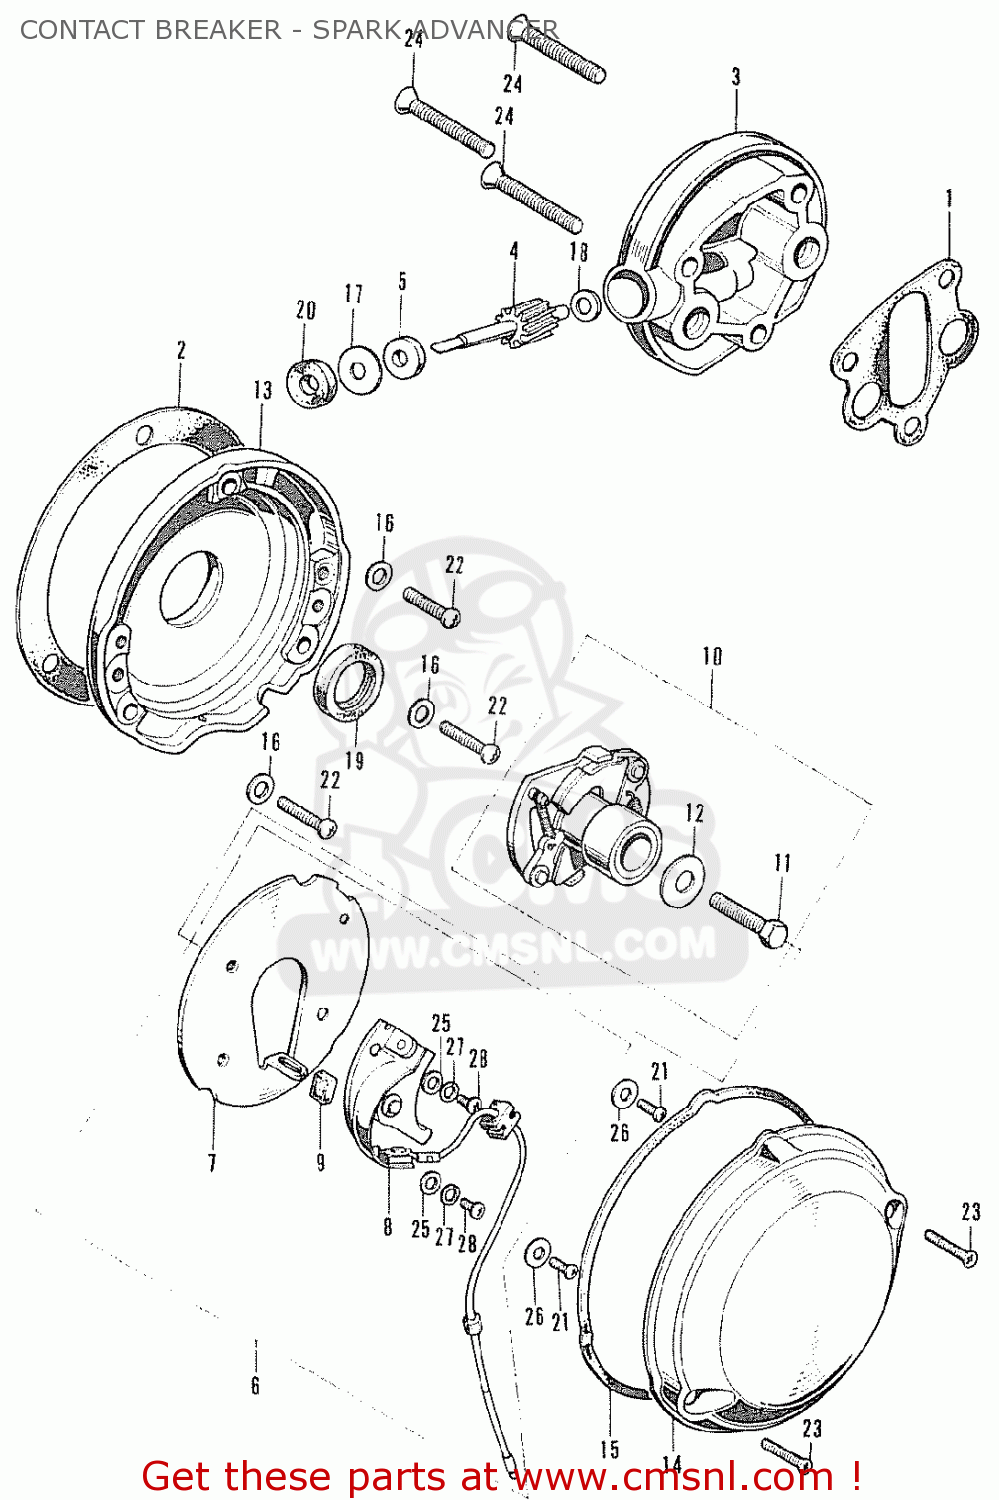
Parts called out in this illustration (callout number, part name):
1	GASKET,GEAR BOX (MCA)
2	GASKET,POINT BASE (MCA)
3	BOX,TACH GEAR
4	GEAR,TACHOMETER
5	COLLAR,TACHOMETER
6	BREAKER,CONTACT
7	BASE PLATE
8	BREAKER,CONTACT
9	FELT,OIL
10	ADVANCER,SPARK
11	BOLT,ADVANSER
12	WASHER,ADVANSER
13	BASE,POINT
14	BODY,POINT COVER
15	GASKET,POINTCOVER (MCA)
16	WASHER, SEALING
17	WASHER THRUST
18	WASHER PINION
19	OIL-SEAL,15X24X5
20	OIL-SEAL,15X24X5
21	SCREW,CROSS 5X8
22	SCREW,CROSS 6X20
23	SCREW,OVAL,5X16
24	SCREW,CROSS,6X32
25	WASHER,4MM
26	WASHER,PLAIN,5MM
27	WASHER,SPG.,4MM
28	SCREW 4X6
